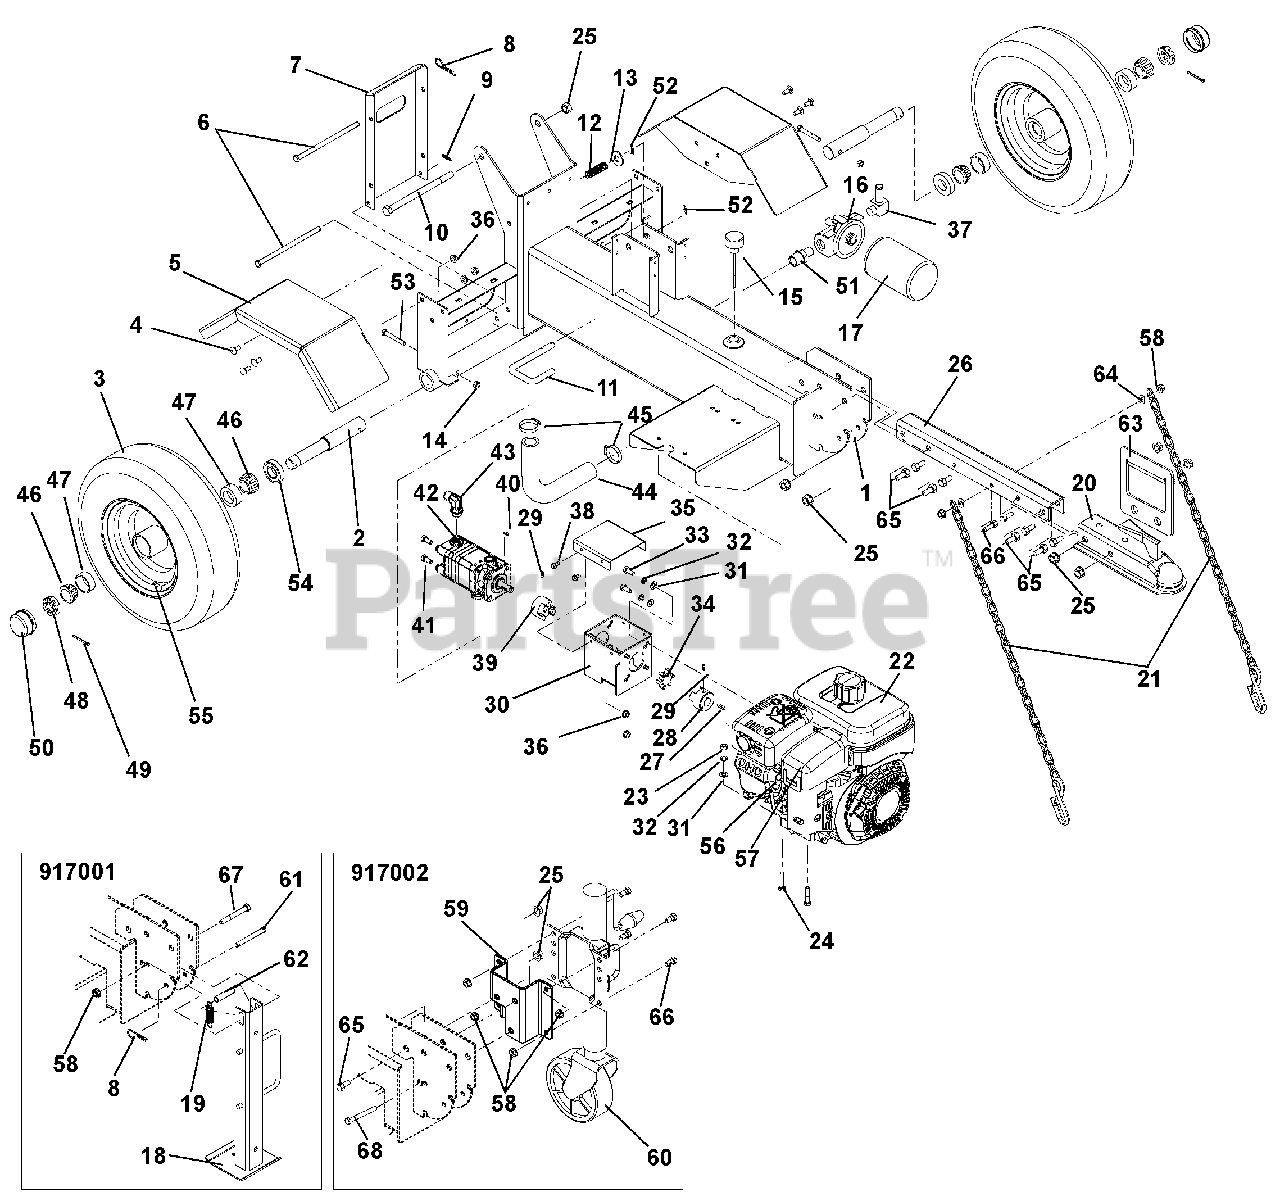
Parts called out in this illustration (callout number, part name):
1	CHASSIS,SPLITTER W/SAFTY DECAL
2	AXLE, SPLITTER
3	WHEEL, SPLITTER
4	@BLT-RDHDSQNK .31-18X.75 G5YZ
5	WLDMT, FENDER
6	PIN, LOCK
7	REAR STAND W/DECALS (ARIENS)
8	HAIRPIN, #7 CLIP .094X2.31 YWZ
9	PIN-HAIR, ENDRIES #25 YWZC
10	@BLT-HEX .50-13X7.50 GR5 YWZC
11	LOCK, BEAM
12	SPRG, COMP .058X.65X2.13 WLD15
13	@WSHR-FL-STL.563X1.38X.109YWZC
14	@NUT-LK-CTR .31-18 YWZC
15	BREATHER, DIPSTICK
16	HEAD,FILTER-3/4 NPT BYPASS
17	FILTER,OIL-W/BYPASS
18	WLDMT, JACK STAND
19	SPRG, TENSION .063X.625X2.50
20	HITCH, BALL-2"
21	CHAIN, SAFETY 3/16"-30LINK
22	ENGINE,SUBARU 6HP SP170 (CARB)
22	ENGINE,SUBARU EX210DT1032-MP
23	@NUT-HEX .31-18 YWZC
24	@BLT-HEX .31-18X1.50 GR5 YWZC
25	NUT-LK-CTR-FLG .50-13 YWZC
26	BAR, HITCH - WITH DECALS
27	KEY-SQ .188X.75X.188
28	COUPLER - DRIVE, 3/4"
29	SCR,SET .25-20X.75 PCPT SH
30	WLDMT, PUMP MOUNT BRKT
31	@WSHR-FL-STL.344X.688X.065YWZC
32	WSHR-LK .312X.097 HVY YWZC
33	BLT-HEX .31-24X.75 YWZC GR5
34	SPIDER - URETHANE
35	COVER W/DECALS
36	@NUT-LK-TOP-FLG .31-18 YWZC
37	FTG,HYD 4501-10-12-FG
38	SCR-TAP .25-20X.50 HWH TR YWZ
39	COUPLER - DRIVE 1/2"
40	KEY-WDRF .125X.50X.20 (HRDEND)
41	@BLT-HEX .31-18X.75 GR5 YWZC
42	PUMP,SPLITTER-11 GPM
42	PUMP,SPLITTER-13 GPM
43	FTG,HYD 6801-8-8
44	HOSE,HYD SUCTION 16G4H X 13.5
45	CLAMP-HOSE 1.50X.81X1.42
46	BRG, CONE W/ GREASE
47	BRG-CUP1.980X.420
48	NUT-SL 1.0-14
49	@PIN-CTR .15X1.50 YWZC
50	CAP, DUST
51	FTG,HYD 5404-12-12
52	CLIP, SPRING
53	@BLT-HEX .31-18X2.25 GR5 YWZC
55	VALVE STEM ASS'Y
56	SPARK PLUG,SP-170
57	FILTER,SP-170 SPONGE/ROBIN
58	@NUT-LK-TOP-FLG .38-16 YWZC
59	BRACKET, MOUNTING
60	STAND, JACK-W/WHEEL
61	PIN-CLEV .371X3.25 YWZC
62	SPCR, WHEEL .385X.500X2.00
63	HANDLE, SPLITTER DRAW BAR
64	@WSHR-FL-STL.406X.812X.065 YWZ
65	@BLT-HEX .50-13X1.00 GR5 YWZC
66	@BLT-HEX .38-16X1.00 GR5 YWZC
67	@BLT-HEX .38-16X3.00 GR5 YWZC
68	@BLT-HEX .38-16X3.25 GR5 YWZC
